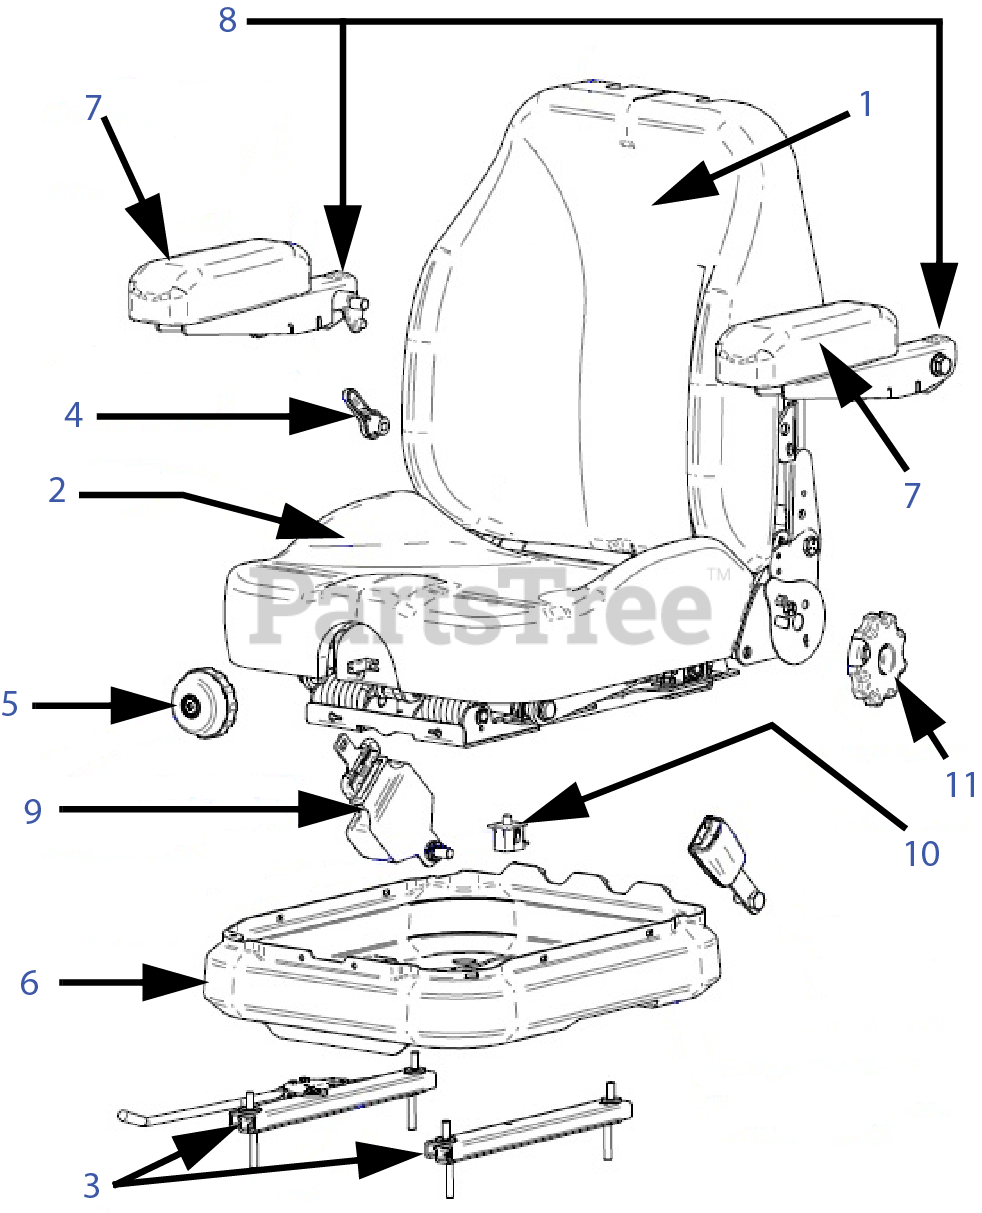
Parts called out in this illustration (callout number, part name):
1	BACK COVER WITH LOGO
3	7" SINGLE LOCKING TRACK - 1.75"
4	ISO LEVER W/ROLL P
5	KNOB ASSEMBLY-WEIGHT A
6	BELLOWS-W/HARDWARE
7	SET OF ARM PADS
8	SET OF FRONT ADJUST ARMS PADDED
9	2" RETRACTABLE SEAT BELT KIT
10	PLUNGER SWITCH NC/NC
11	SEAT KNOB KIT
